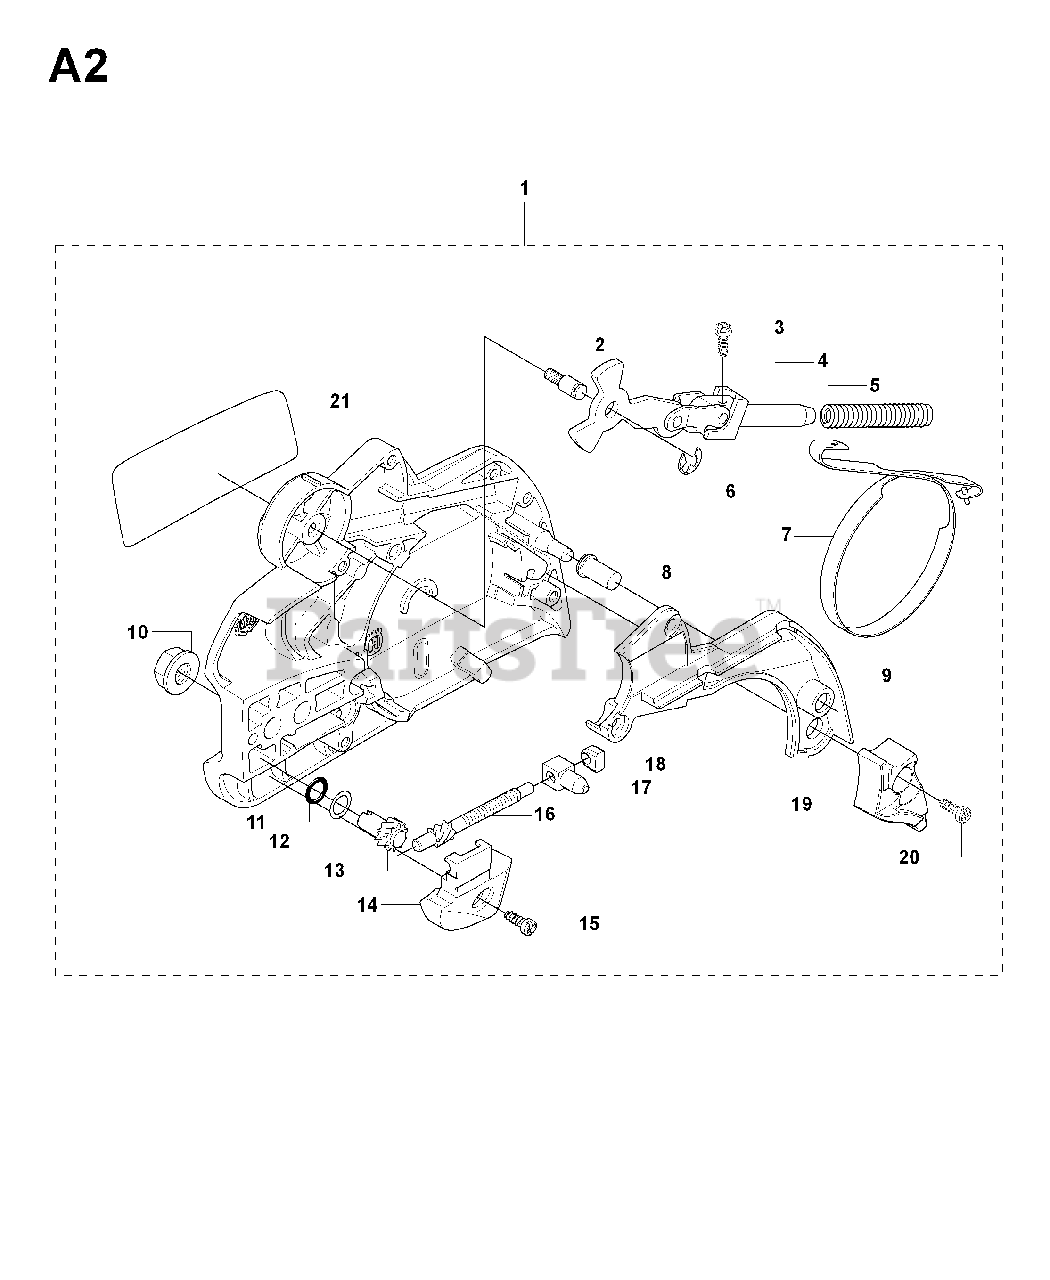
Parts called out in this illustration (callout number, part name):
1	CLUTCH COVER ASSY
7	BRAKE BAND
10	NUT M8 FLANGE
16	SCREW
19	PROTECTOR
